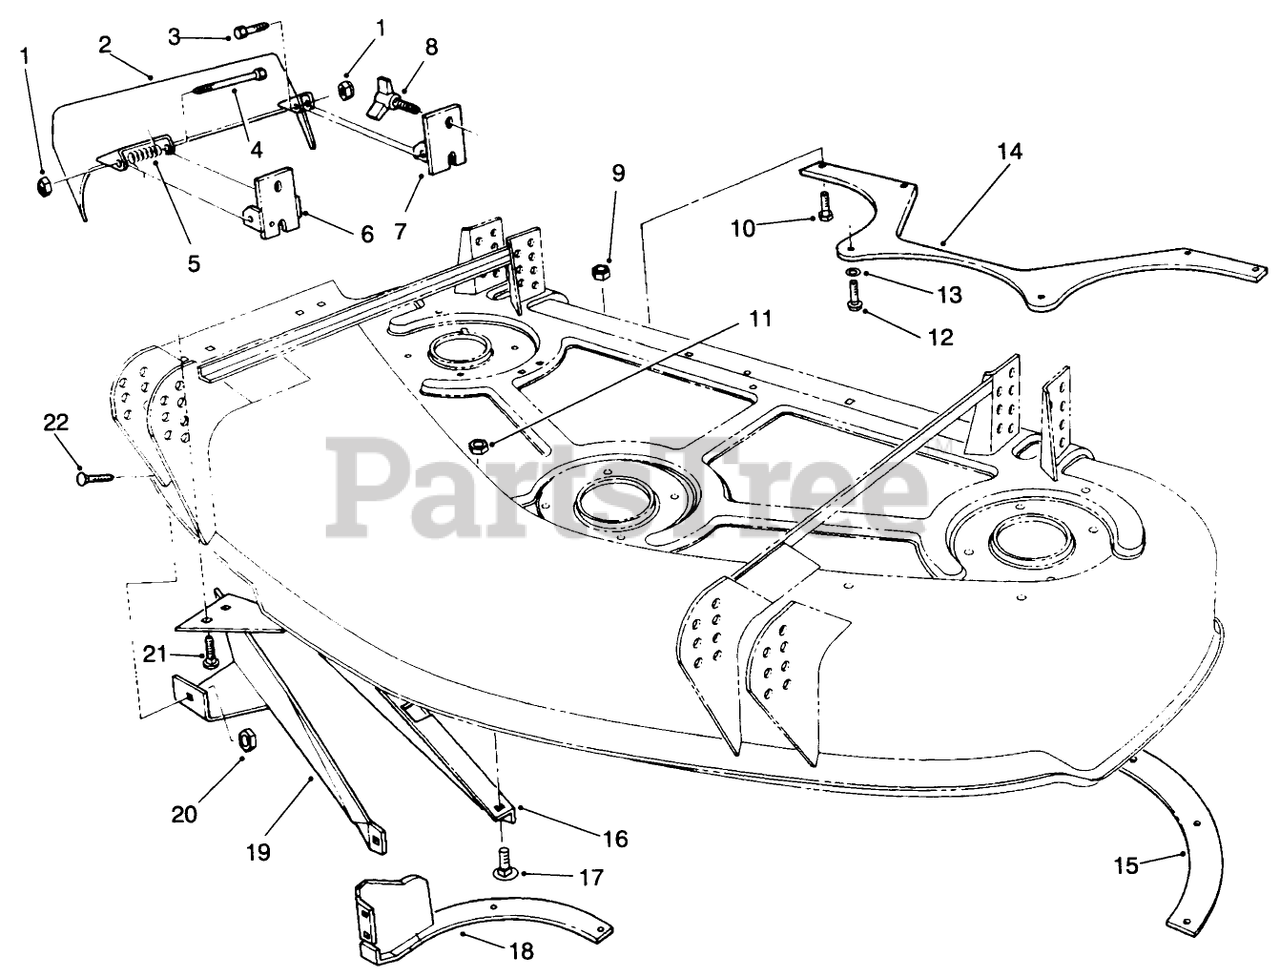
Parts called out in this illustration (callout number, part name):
1	NUT-HEX
2	Deflector-Grass (Incl. Ref. #23)
3	SCREW-HH
4	SCREW-HH
5	SPRING
6	Bracket-Pivot RH
7	Bracket-Pivot LH
9	NUT-LOCK, NI
10	SCREW-HH
11	NUT-KEPS
12	SCREW-HWHTF
13	WASHER-FLAT
14	Baffle Bagging
15	RING - LH BAGGING R
16	Baffle-Rear
17	SCREW-CARR
18	Ring-Bagging RH
19	Baffle-Front
20	NUT-KEPS
21	BOLT-CARR
22	SCREW-CARRIAGE
23	DECAL-DANGER
